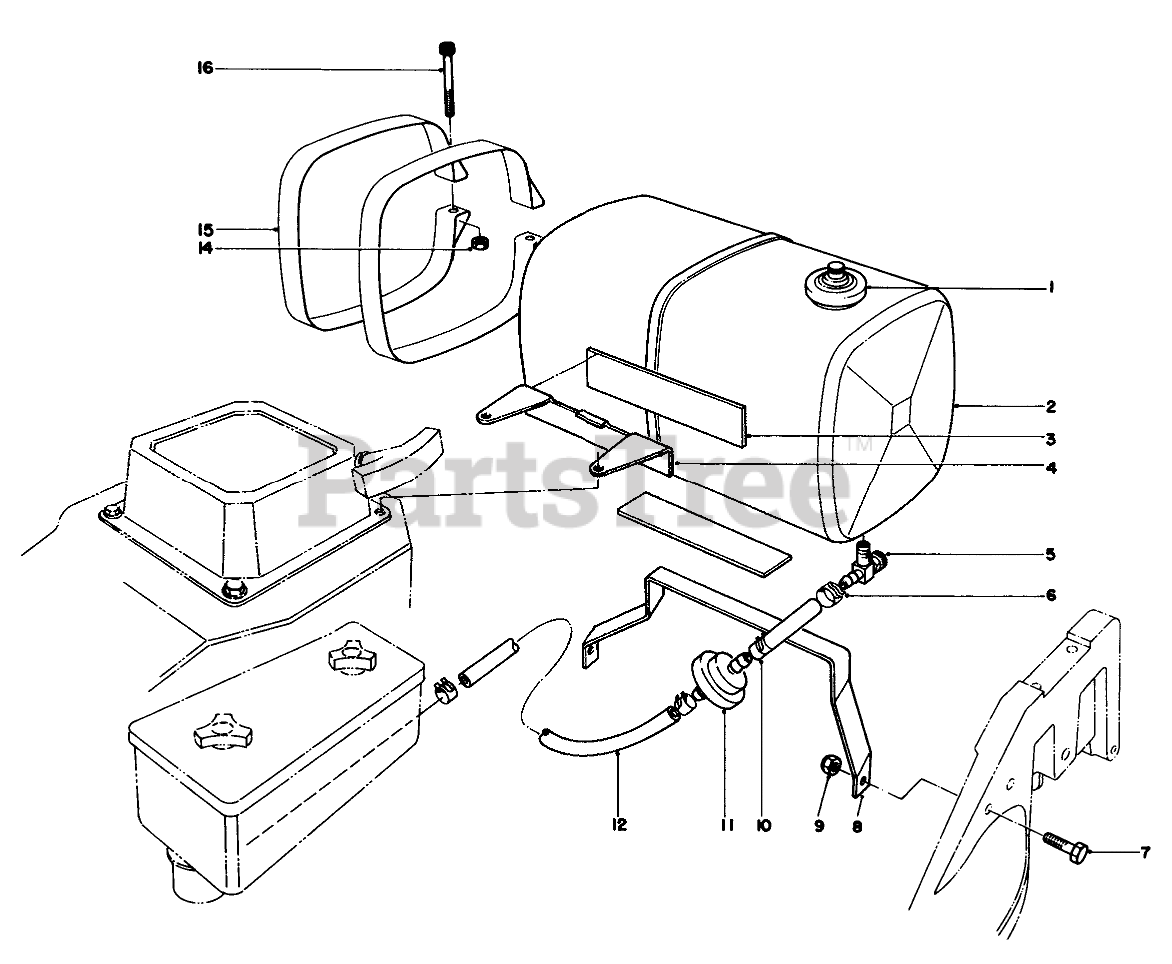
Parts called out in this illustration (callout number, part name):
1	GAS CAP
2	Gas Tank (Incl. Ref. #1)
3	ISOLATOR PAD
4	Mount-Tank Front
5	.125 ID SHUTOFF VALVE
6	CLAMP-FUEL LINE
7	SCREW-HH
8	BOTTOM TANK SUPPORT
9	NUT-LOCK, NI
10	LINE-GAS
11	FILTER-FUEL
12	HOSE-FUEL
14	NUT-HEX
15	TANK STRAP WA
16	SCREW-HSH
